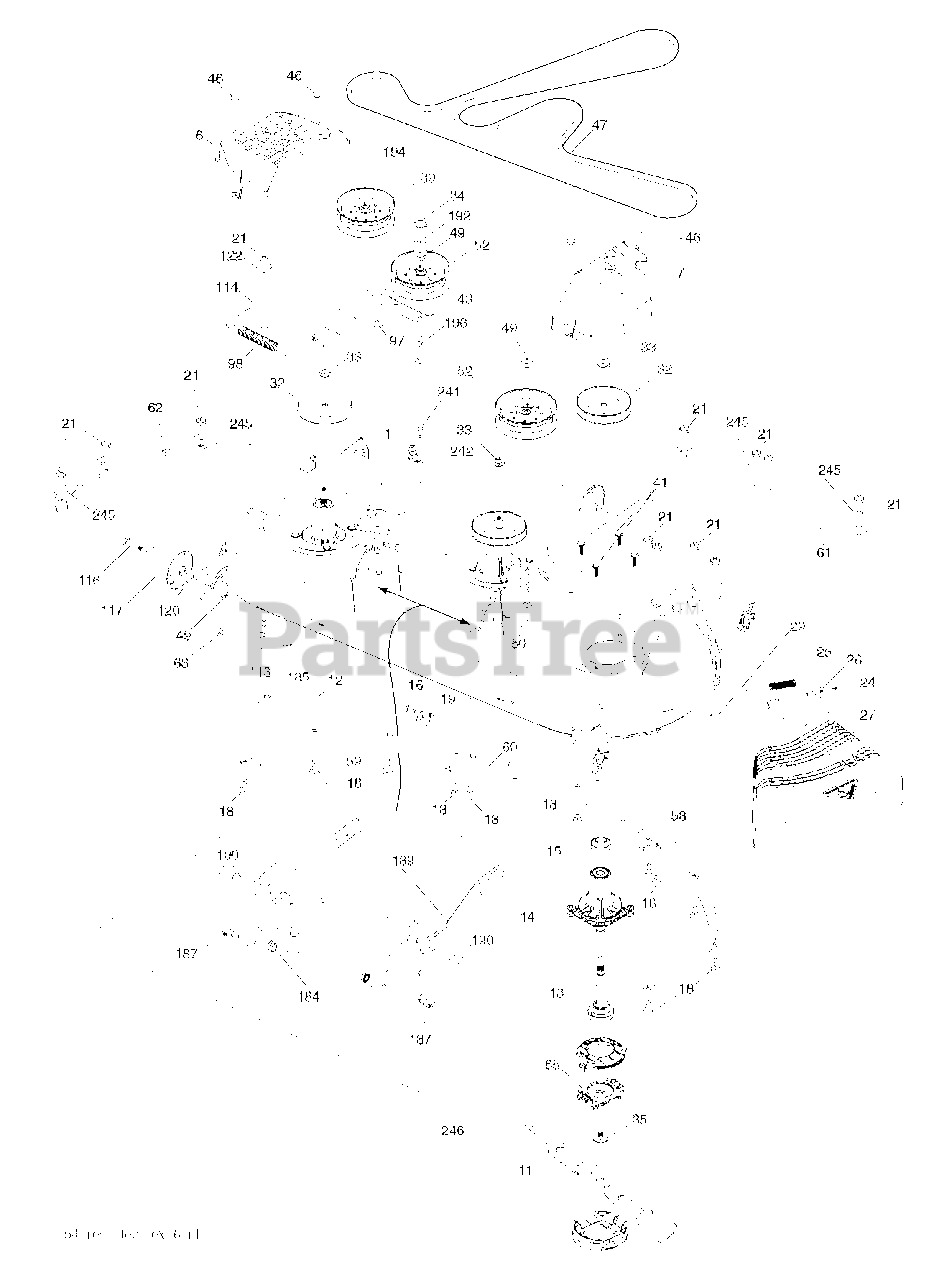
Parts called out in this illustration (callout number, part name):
1	DECK SVC 54"
6	COVER.MANDREL.LH.54"20
7	COVER.MANDREL.RH.54.20
11	BLADE.BAGGER.54"
12	ROD.ANTI.SWAY.48/54"TE
13	MANDREL.ASM.REV.TALL.N/GRSABLE
14	HOUSING.MANDREL.REV.TALL.GRSBL
15	BEARING.MANDREL.TOP.EXTENDED
16	WASHER
18	BOLT
19	PIN.COTTER.5/16.BOW TI
21	LOCKNUT
24	CAP-SLEEVE LT
25	SPRING, TORSION
26	NUT PUSH M
27	DEFLECTOR
29	ROD.HINGE
32	PULLEY/MANDREL
33	NUT.FLANGE.LOCK.TOP
35	SCREW.SEMS.7/16-20X1.HEX.HEAD
39	RB PULLEY.IDLER.4.50/HUB SPEC
41	BOLT.HEX.WASHR.HED.313-18X1.19
46	SCREW.1/4-20X5/8
47	BELT.DECK.DRIVE.BELT.54
49	NUT LOCK FLG 3/8-16 UNC
52	PULLEY.IDLER.2006
58	BAFFLE.RIGHT.54"
59	BAFFLE.LEFT.54"
60	BAFFLE CENTER 54" MOWER
61	PLATE.REIN.FRONT.BOLT54"X431
62	PLATE.REIN.SIDE.BOLT.54"X431
63	BOLT.CARRIAGE.5/16-18
65	HOLDER.BLADE.REVOLUTION
98	SPRING, DECK DRIVE
114	ROD TENSION RELIEF
116	BOLT.SHOULDER.3/8-16X3-5/8.
117	WHEEL. GUAGE RALLY
120	WASHER
122	BUSHING.RELIEF.TENSION
184	NUT LOCK HEX FLANGE 5/16-18
185	NUT.LOCK.FLANGE.7/16
187	STUD.FASTNER.W/ANTI-ROTATE
189	ARM.SUSPENSION.MOWER
190	BOLT.SHOULDER
192	KEEPER.BELT.IDLER.54"T
194	BOLT.HEX.WASHER.HEAD.7/16-24X
241	SCREW.TT.#10-32X.5.3/8.FLANGE
242	PORT.WASHOUT
245	WASHER
246	CAP.REVOLUTION ASM
